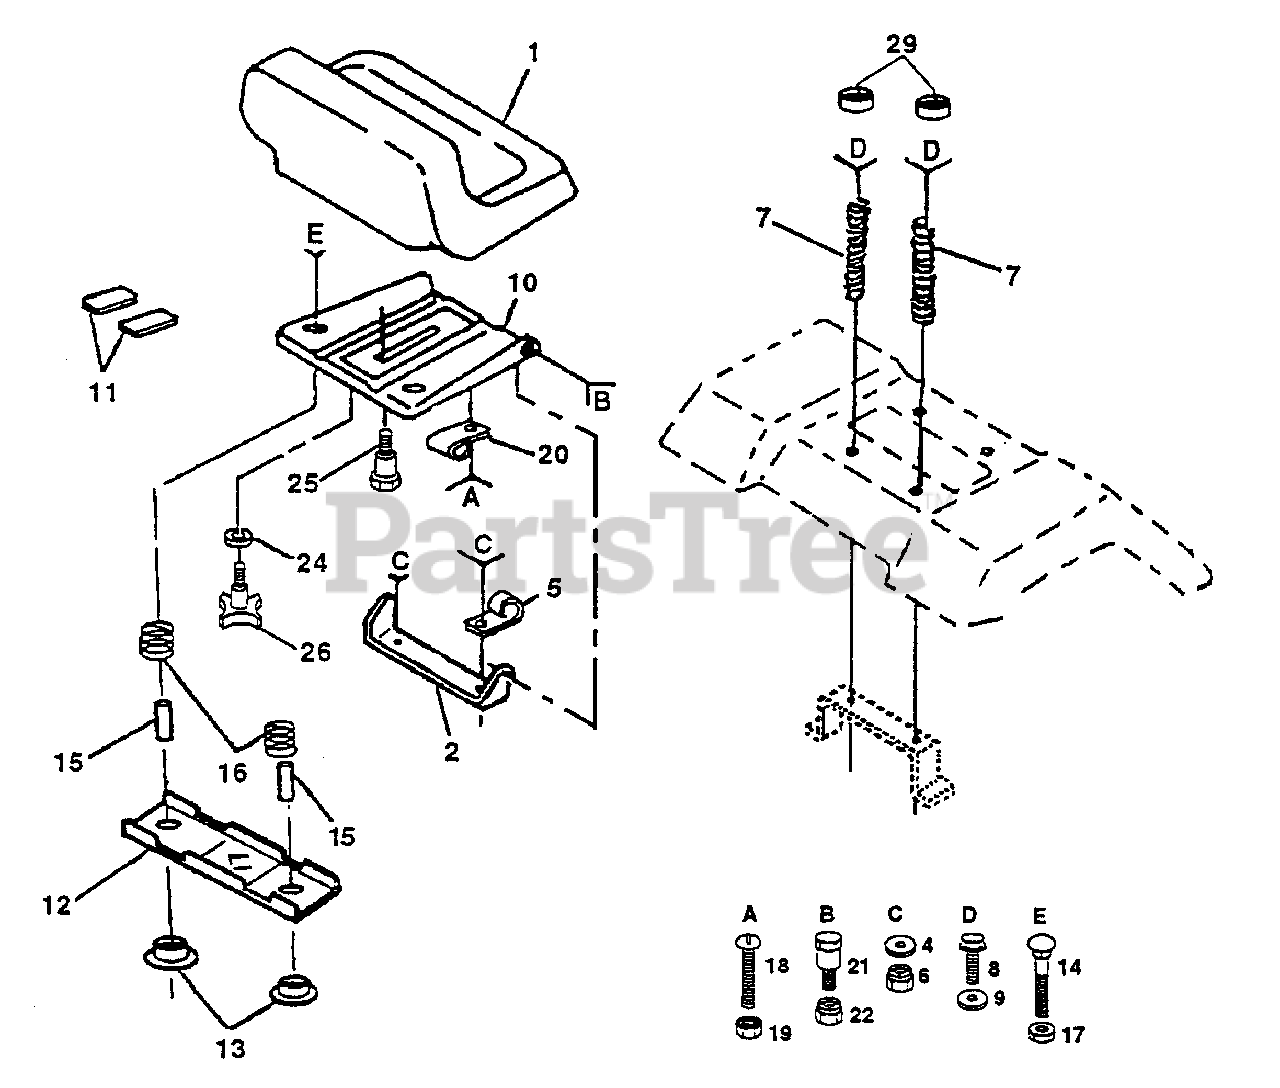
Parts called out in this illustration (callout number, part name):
1	Seat V-550 Gry/blk Std
2	Bracket Pivot Seat 8 720
4	Washer 13/32 X 3/4 X 10 Ga
5	Clip Line Fuel 13/32 Mtg Hole
6	Nut Crownlock 3/8-16 Unc
7	Spring Seat Cprsn 2 250 Blk ZI
8	Screw Hwsh Thdrol 5/16-18 x 1/2
9	Washer 13/32 X 1 X 14 Ga
10	Pan Seat
11	Strip Foam Gray Or Black
12	Bracket Mounting Switch
13	Bushing Snap Blk Nyl 50 Id
14	Bolt Rdhd Sht Nk 1/4-20x1-3/8
15	Spacer Split 28x 88 Yel Zinc
16	Spring Cprsn 1 310 Blk Pnt
17	Nut Lock 1/4 Lge Rg Gr 5 Zinc
18	Screw SLTD Pan Hd #10-32 X 1/2
19	Nut Keps #10-32 Unt
20	Clip Insulated 11/32 Mtg Hole
21	Bolt Shoulder 5/16-18 Unc Blkz
22	Nut Crown Lock 5/16-18
24	Washer 17/32 X 1-3/16 X 12 Ga
25	Bolt Shoulder 5/16-18 X 62
26	Knob Seat 1/2-13unc Blk
29	Cap Spring Seat
